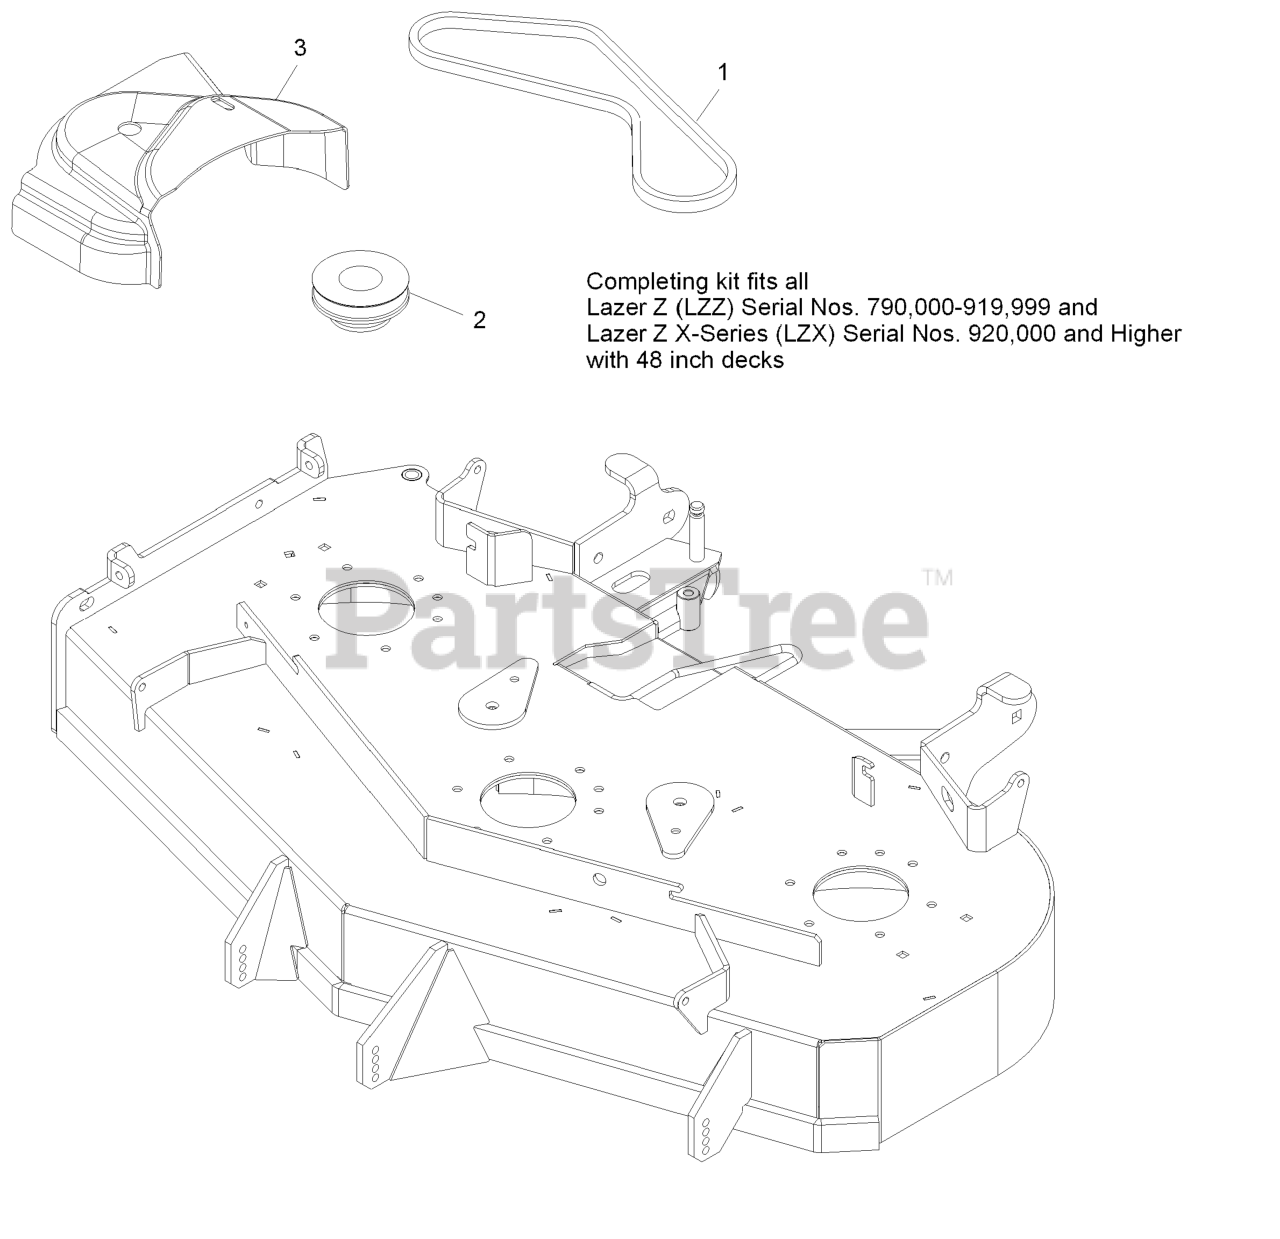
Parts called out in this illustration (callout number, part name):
1	Belt, Blower (48")
2	Blade, Extreme 72
3	Cover,Belt Uv 48
